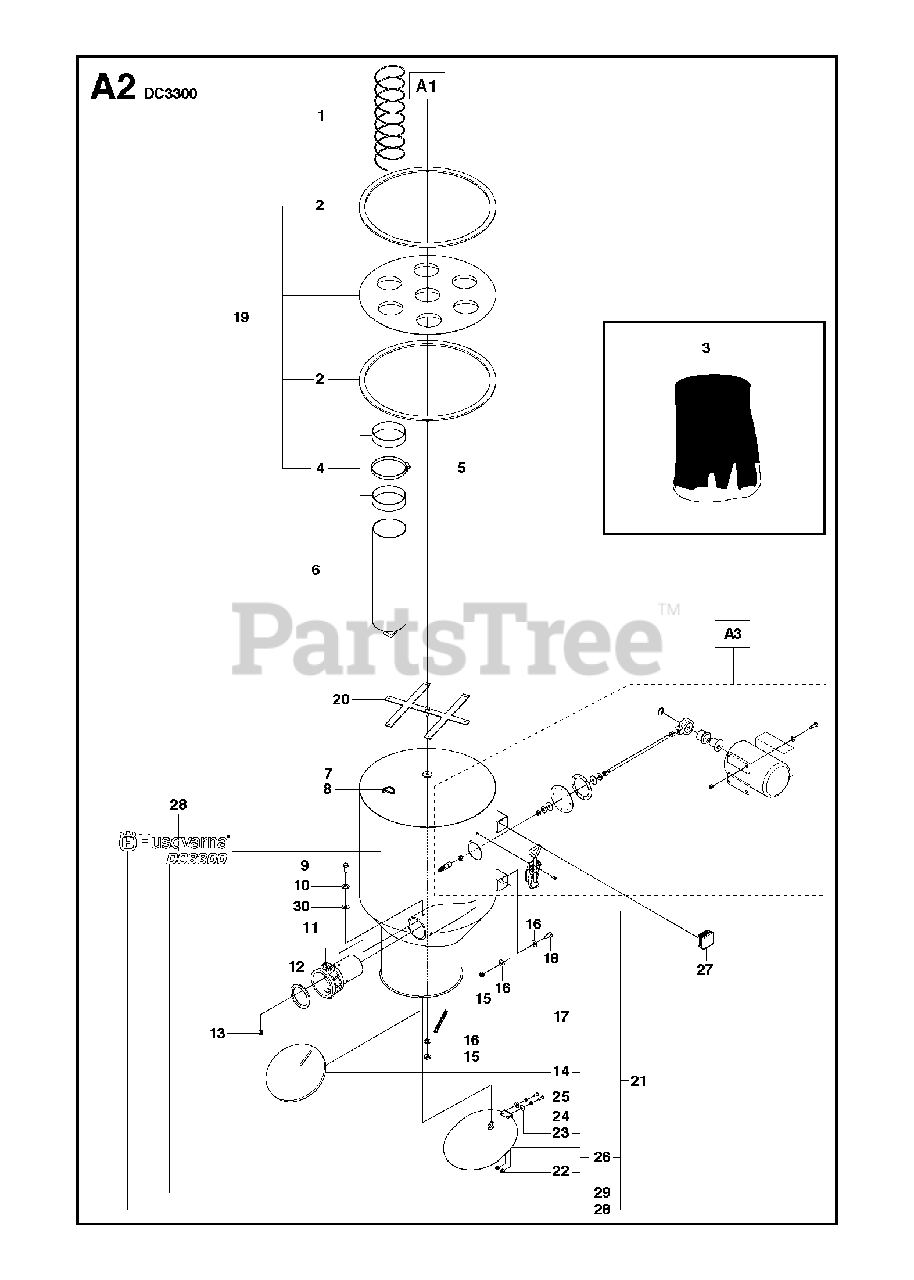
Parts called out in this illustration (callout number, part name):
10	WASHER
13	HEXAGON LOCKING NUT
15	HEXAGON LOCKING NUT
16	WASHER
22	HEXAGON LOCKING NUT
